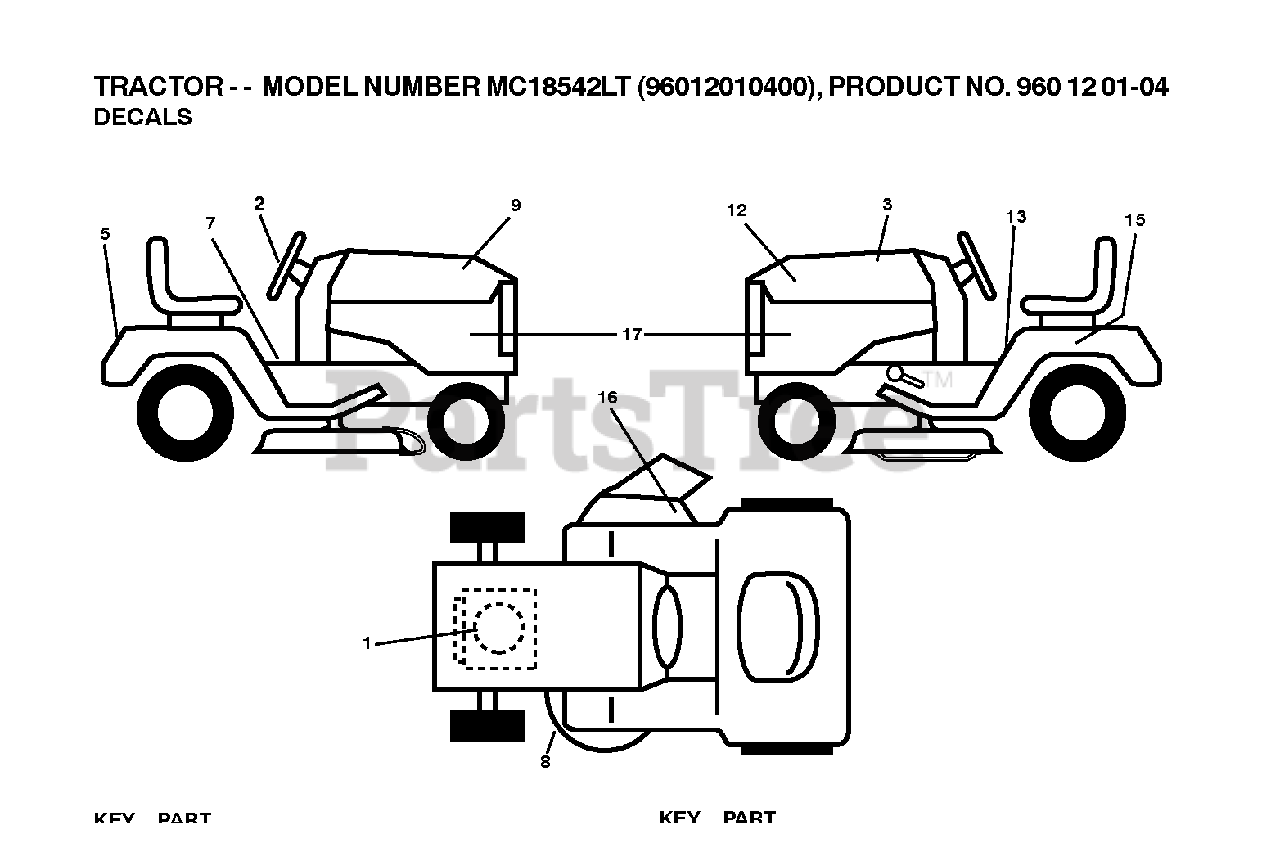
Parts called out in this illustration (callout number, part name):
1	DECAL.ENG.BS.5HP.PB.278978
3	DECAL.RPL.PMST.42C.BS.175.STL
8	DECAL V BELT SCHEMATIC
10	DECAL SERVICE
13	Fender Warning Decal, English
15	DECAL BTRY SYMBOLS
